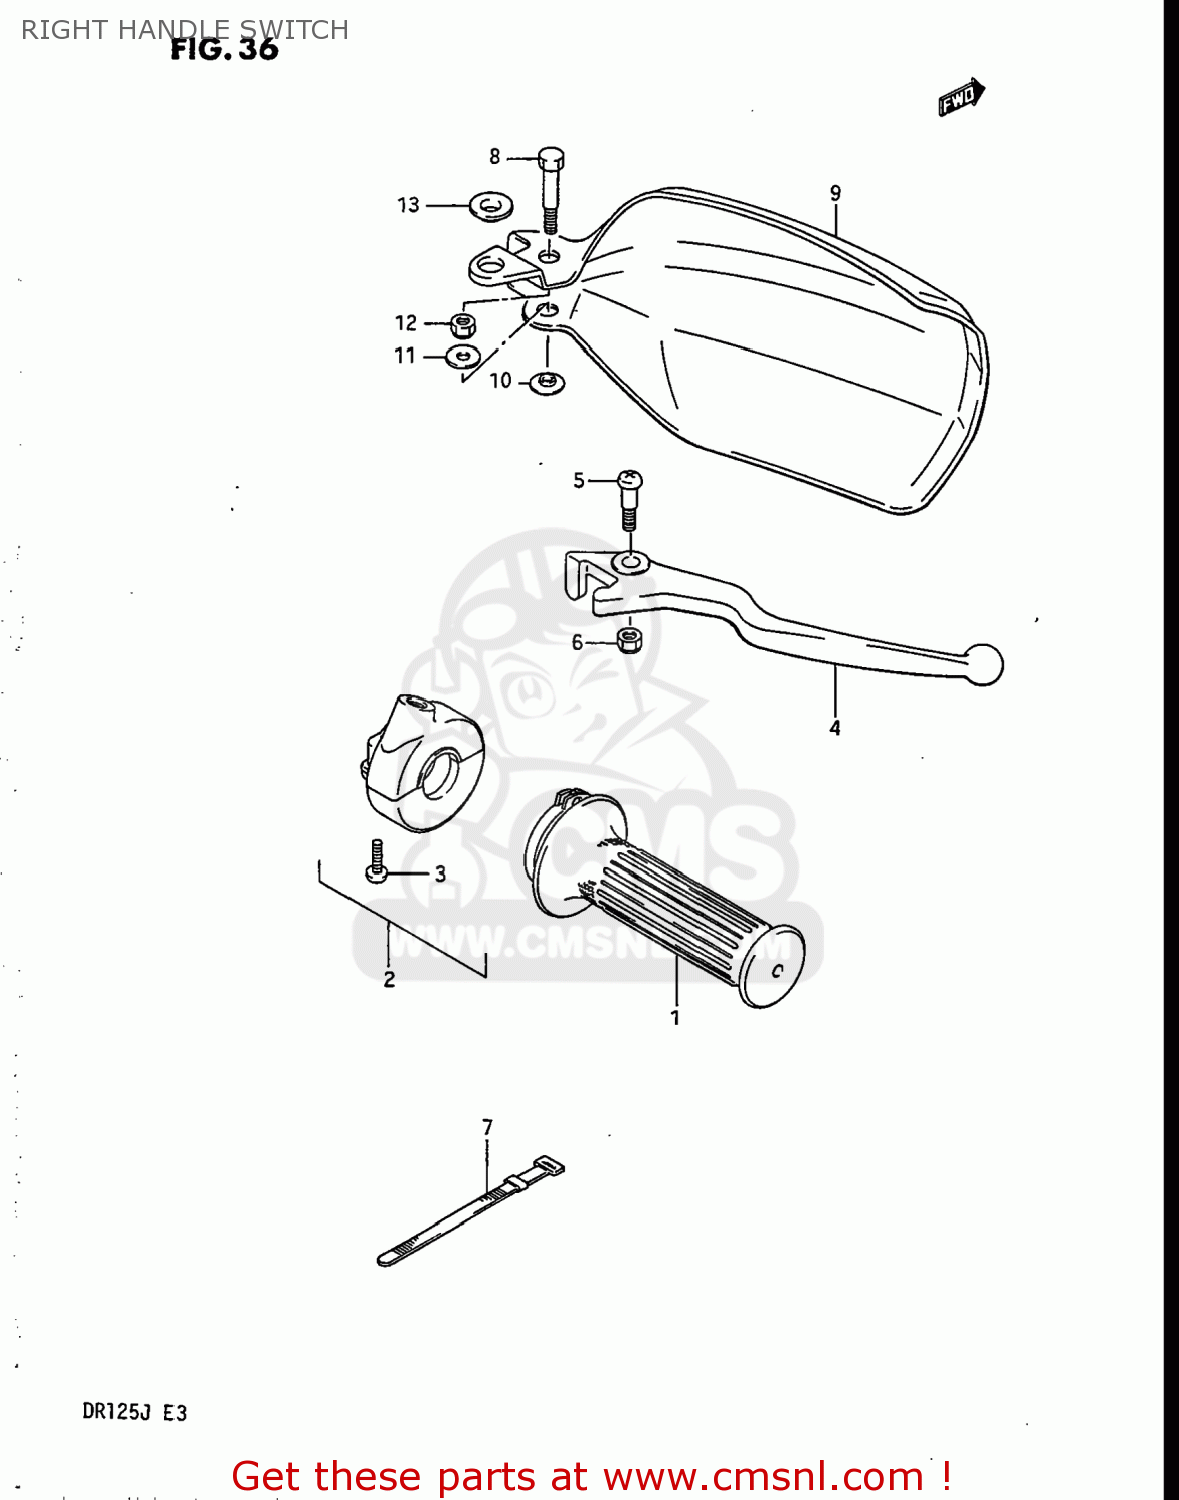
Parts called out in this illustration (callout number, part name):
1	GRIP,THROTTLE
2	CASE ASSY,THROTTLE
3	SCREW 5X20
4	LEVER,BRAKE
5	SCREW
6	NUT
7	CLAMP(L:120)
8	BOLT,LEVER PIVOT
9	COVER,KNUCKLE,RIGHT
10	WASHER
11	WASHER(6.5X16X1.2)
12	NUT 6MM
13	WASHER
